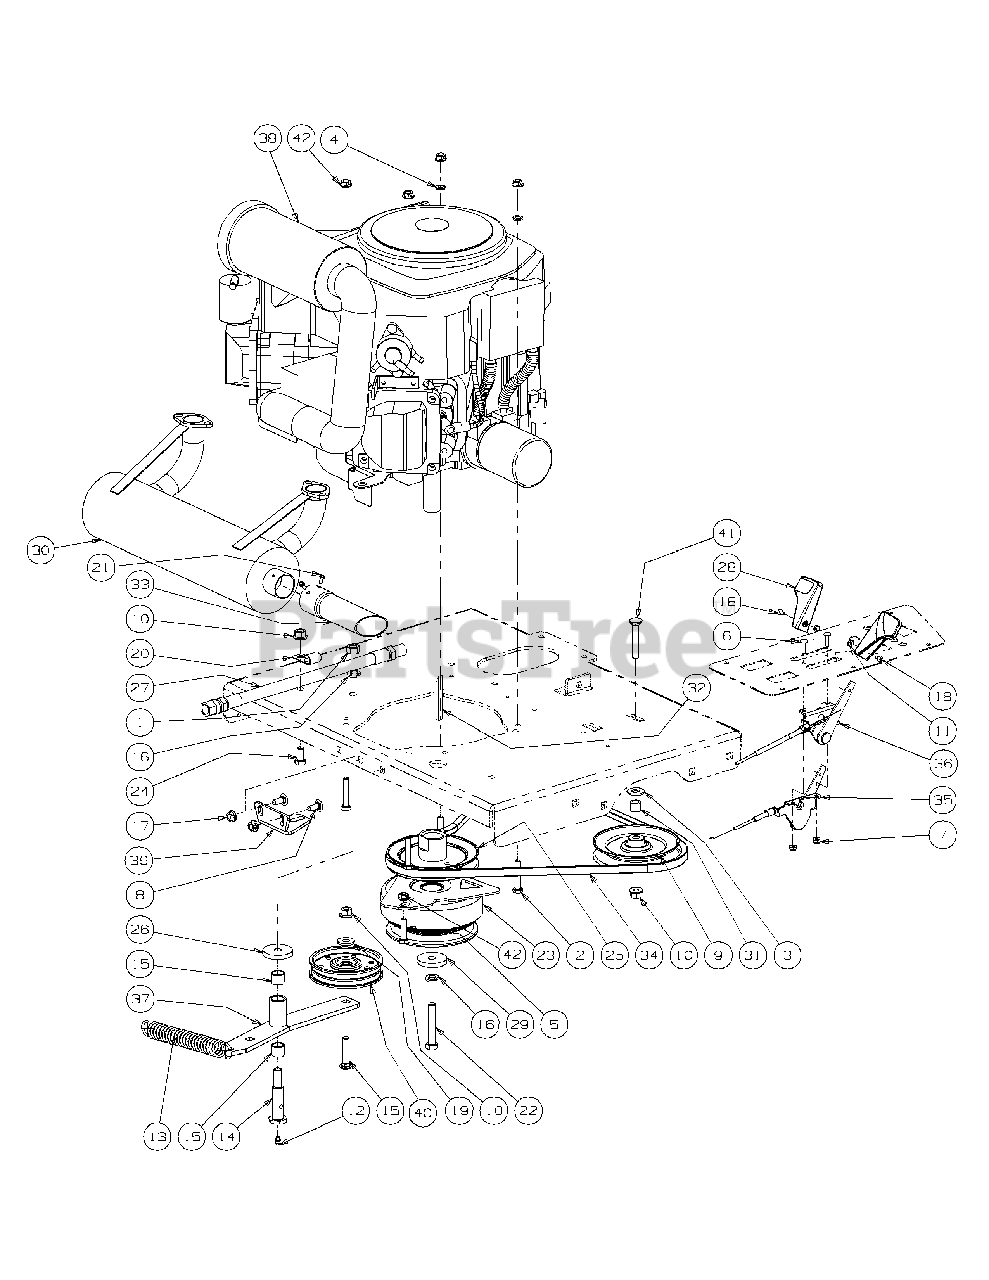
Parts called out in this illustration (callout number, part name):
1	Hex Nut, 7/16-14
2	HHCS, 5/16-18, 1-3/4
3	Flat Washer, 3/8 zinc
4	Flat Washer, .320 ID x .591 OD x .078
5	HHCS, 5/16-18 x 1-1/4
6	Round Hd. Machine Screw, 10-32 x 3/4
7	Lock Nut, Nylon Insert, 10-32
8	Carriage Bolt, 5/16-18 x .75
9	Idler Pulley
10	Flange Lock, Hex Nut, 3/8-16
11	Nut Washer, W/Star, 8-32
12	Grease Fitting, 1/4-28 x 3/16
13	Spring Extension, 1.0 OD x 5.00S
14	Shoulder Screw, 7/16-14
15	Hex Carriage Screw, 3/8-16, 1.75
16	Lock Washer, 7/16
17	Hexflange Lock Nut, 5/16-18
18	Machine Screw, 8-32, .375
19	Flat Washer, .406 ID, 1.0 OD, .105
20	Clip, Heat Shield Cable
21	Screw, #8-32 x 0.375
22	Capscrew, 7/16-20 x 2.50
23	Clutch Brake, 1.125 ID
24	Hex Cap Screw, 3/8-16, .750
25	Pump Drive Pulley
26	Flat Washer, 7/16 ID x 1.75 OD x .25
27	Oil Drain Hose
28	Control Throttle Knob
29	Flat Washer, 7/16 ID x 1.75 OD x .25
30	Muffler Accessory Kohler
31	Spacer, 1.50 OD x .385 ID x .585
32	Key, 1/4 x 1/4 x 2.75
33	Exhaust Pipe
34	Belt, 50.125 Lg
35	Throttle, Control Cable
36	Choke, Control Cable
37	Engine Idler Arm Assembly Includes:
38	Engine, 25HP Kohler
39	Retainer Clutch Assembly
40	Flat Pulley with Flanges
41	Carriage Bolt, 3/8-16 x 2.25
42	Nut, 5/16-18, Flangelock
